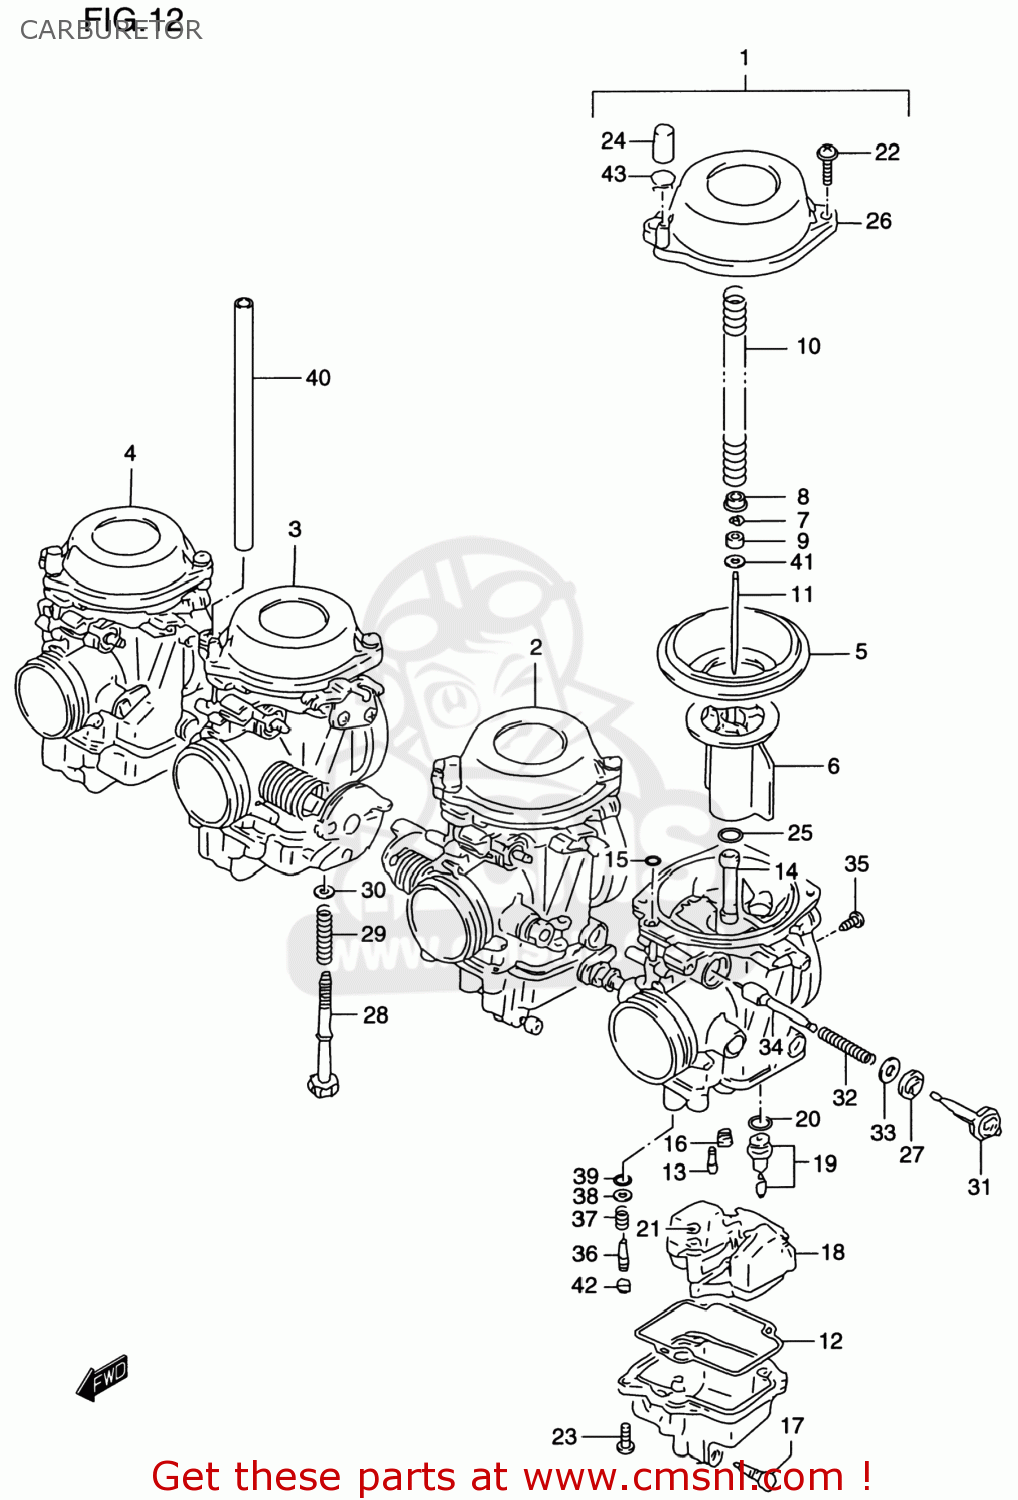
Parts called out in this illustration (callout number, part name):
1	CARBURETOR ASSEMBLY,LEFT
2	CARBURETOR ASSEMBLY,MIDDLE,LEFT
3	CARBURETOR ASSEMBLY,MIDDLE,RIGHT
4	CARBURETOR ASSEMBLY,RIGHT
5	DIAPHRAGM
6	VALVE,PISTON
7	E RING
8	RING
9	RING
10	SPRING
11	NEEDLE,JET(5D80)
12	GASKET,FLOAT CHAMBER (NAS)
13	JET,PILOT(37.5)
14	JET,NEEDLE(O-8M)
15	O RING
16	JET,MAIN(102.5)
17	SCREW,DRAIN
18	FLOAT ASSY
19	VALVE ASSEMBLY,NEEDLE
20	O-RING,NEEDLE VALVE
21	O RING
22	SCREW
23	SCREW
24	CAP
25	O RING
26	COVER,DIAPHRAGM
27	CAP,STARTER
28	SCREW,ADJUSTER
29	SPRING
30	WASHER
31	HOLDER,GUIDE
32	SPRING
33	WASHER
34	PLUNGER ASSY
35	JET,PILOT AIR(1.5)
36	SCREW,PILOT
37	SPRING
38	WASHER
39	O RING,PILOT AIR SCREW
40	HOSE(5X9X600)
41	WASHER
42	PLUG
43	CLIP
